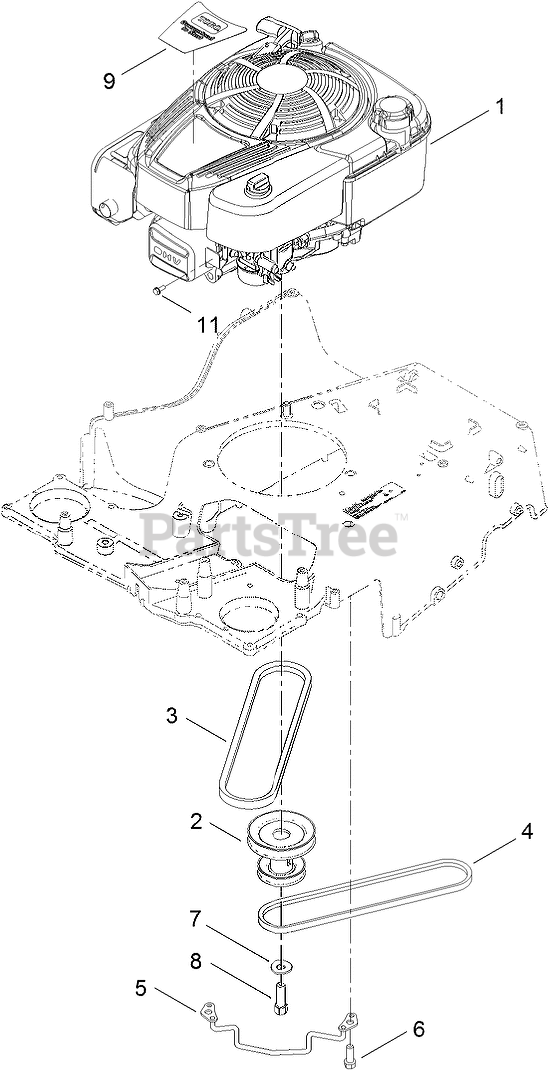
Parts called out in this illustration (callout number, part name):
2	PULLEY-ENGINE
3	V-BELT
4	V-BELT, TRACTION
5	GUIDE-BELT
6	SCREW-TAPTITE
7	WASHER-BELLEVILLE
8	SCREW-HH
9	DECAL-SHROUD
11	SCREW-TAPTITE
